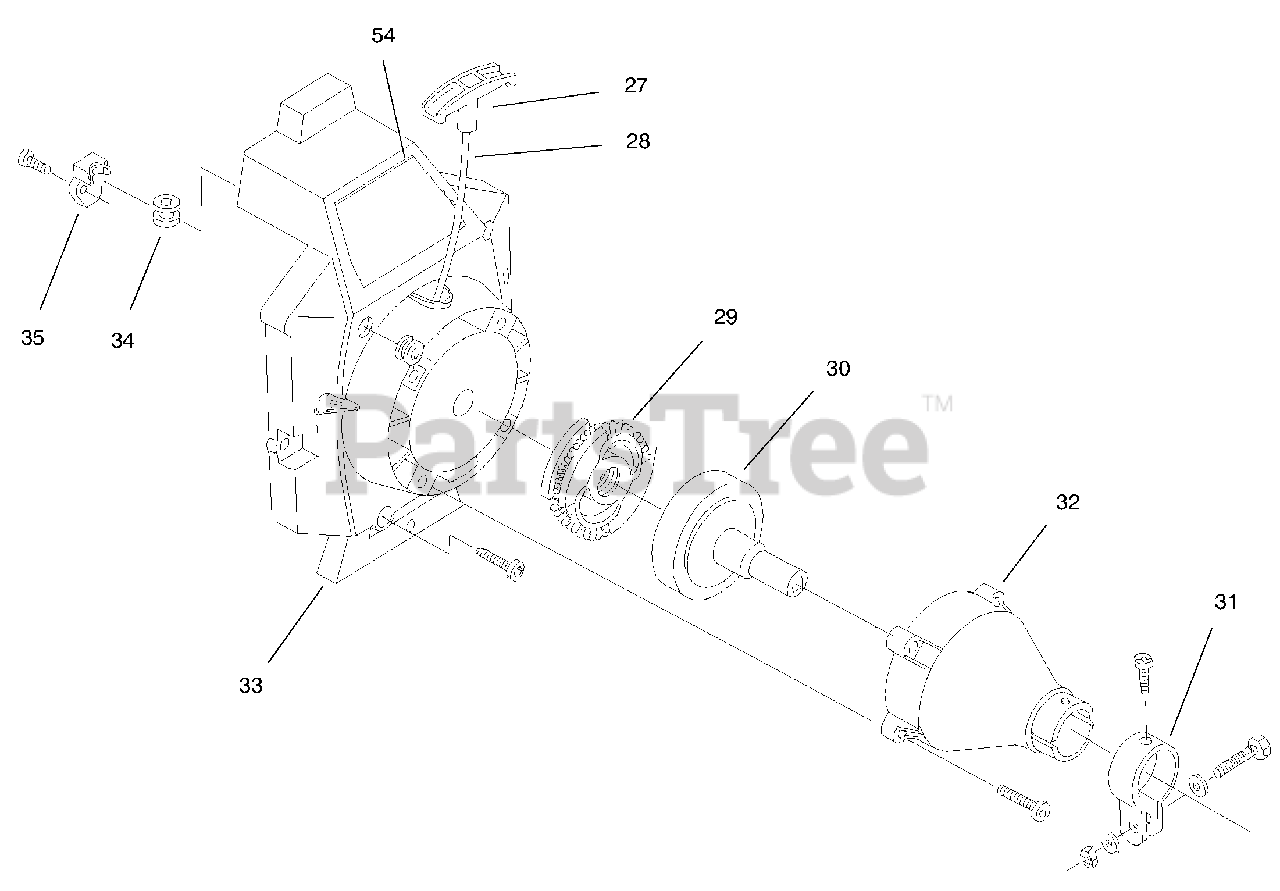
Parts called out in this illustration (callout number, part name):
27	Handle-Pull
29	Clutch Rotor Asm.
30	CLUTCH DRUM ASM
31	CLAMP ASM - UPPER
32	CLUTCH HSG ASM
33	STARTER HSG ASM
34	ROPE GUIDE
35	PULLEY RETAINER ASM
54	DECAL - TORO
